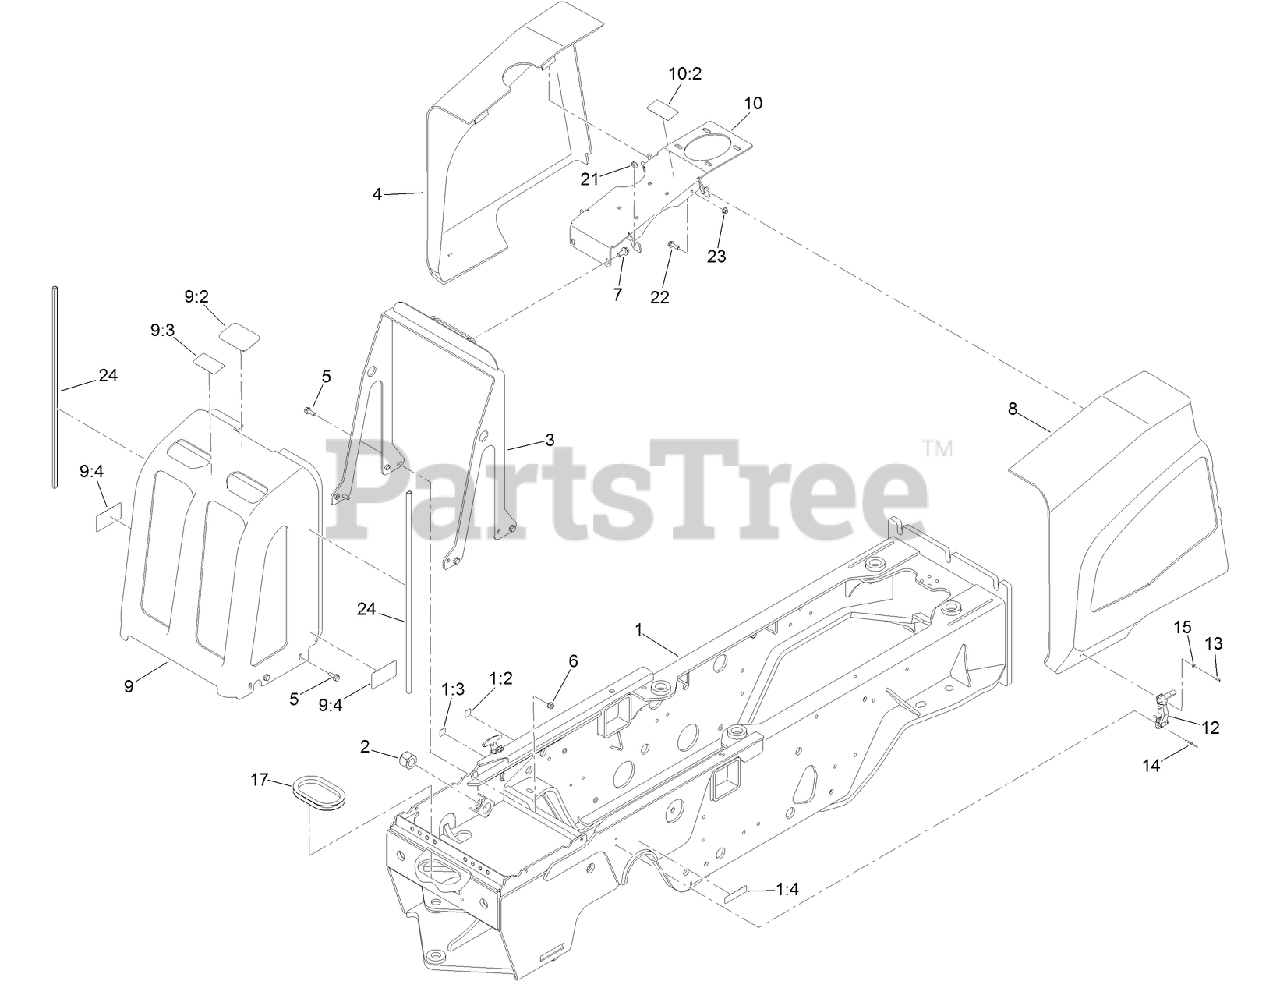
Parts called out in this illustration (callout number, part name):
1	CHASSIS FRAME ASM
1:2	DECAL-FLUID, HYDRAULIC (OUT)
1:3	DECAL-FLUID, HYDRAULIC (IN)
1:4	DECAL-ARRESTER, SPARK
3	SUPPORT-HOOD
4	RT600 RIGHT HOOD
5	SCREW-HHF
6	NUT-LOCK, NI
7	SCREW-HHF
8	RT600 LEFT HOOD
9	NOSE-CLIP W/DECALS
9:2	DECAL
9:3	DECAL-WARNING, RADIATOR
9:4	DECAL-WARNING, FAN
10	HOOD SUPPORT ASM
10:2	DECAL-SURFACE, HOT
12	LATCH-DRAW, FLEXIBLE
13	RIVET-POP
14	RIVET-BLIND
15	WASHER-PLAIN
17	TRIM-EDGE
21	TRIM-BUMPER
22	SCREW-HHF
23	NUT-HF
24	SEAL-BULB
